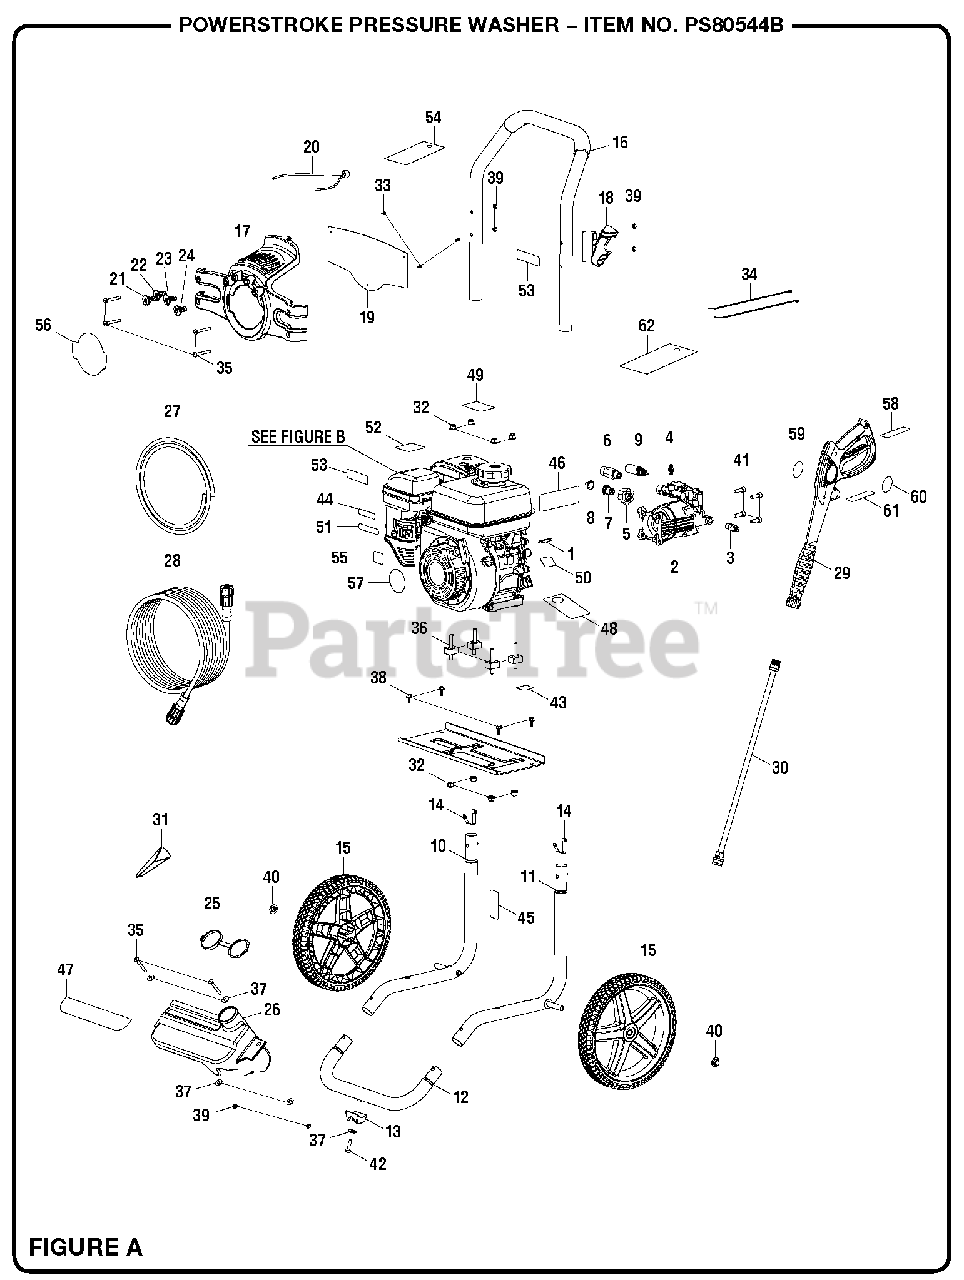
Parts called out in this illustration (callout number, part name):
1	Output Shaft Key
2	Pump
3	Thermal Release Valve
4	Soap Injector Kit
5	Inlet Filter Adapter Insert
6	Outlet Tube
7	Inlet Filter Connector
8	Inlet Filter Screen
9	Unloader Valve Assembly
10	Left Frame Assembly
11	Right Frame Assembly
12	Front Frame Assembly
13	Rubber Foot
14	Handle Spring Clip
15	Wheel (12 in.)
16	Handle Assembly
17	Hose and Nozzle Holder Assembly
18	Wand Holder
19	Instruction Panel
20	Bungee Cord and Bead Assembly
21	0deg Deg Nozzle
22	25deg Deg Nozzle
23	40deg Deg Nozzle
24	Soap Nozzle
25	Soap Tank Cap
26	Soap Tank
27	Chemical Siphon Tube
28	Hose (25 ft.)
29	Trigger Handle Assembly
30	Wand Assembly
32	Flange Lock Nut (M8)
33	Screw (#6-20 x 3/8 in.)
35	Screw (M6 x 48 mm, T30 Torx Hd.)
36	Engine Isolator
37	Washer (1/4 in.)
38	Bolt (M6 x 16 mm, Flange Hd.)
39	Lock Nut (M6)
41	Bolt (5/16-24 x 23 mm, Hex Soc. Hd.)
42	Screw (M6 x 25mm, T-30 Torx Pan Hd.)
43	Add Oil Label
44	Choke Label
45	Combustion Label
46	Danger Label
47	Detergent Tank Label
48	Oil Dipstick Hang Tag
49	E85 Label
50	Engine Switch Label
51	Fuel Label
52	Hot Surface and Exhaust Label
53	Inquiries Label
54	Nozzle Hangtag
55	On/Off Label
56	Performance Label
57	Recoil Label
58	Trigger Handle Warning Label (Fr/Sp)
59	Powerstroke Trigger Wand Logo Label
60	Trigger Handle Warning Label (En)
61	Trigger Handle Specifications Label
62	Danger Hang Tag
